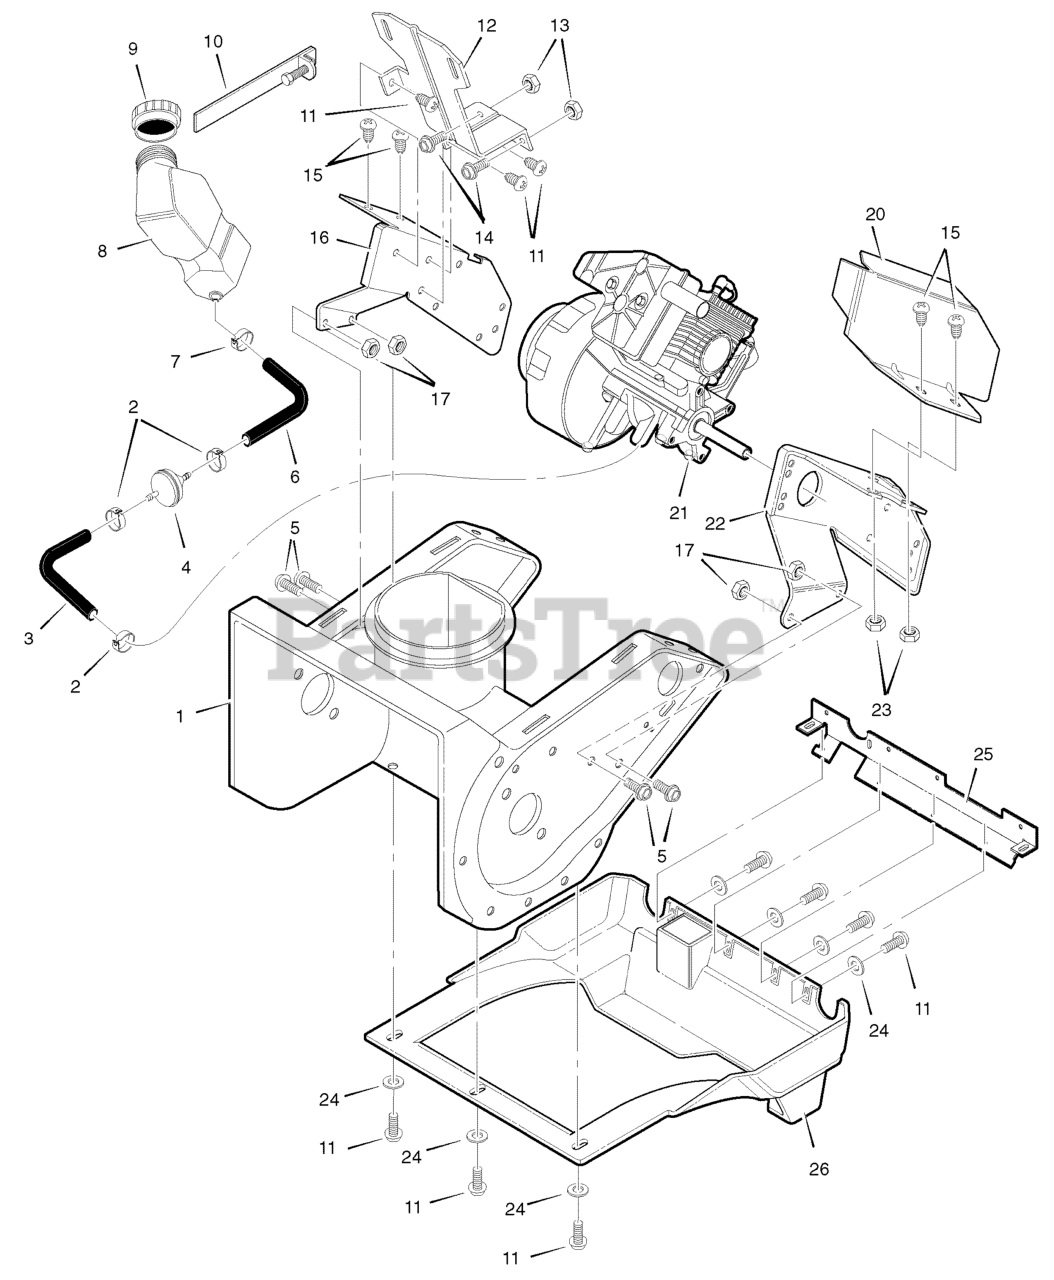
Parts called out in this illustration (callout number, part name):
1	AUGER HOUSING 21"
2	CLAMP, TUBING
3	TUBING, FUEL
4	FILTER, FUEL
5	SCREW .31-18x.50
6	TUBING, FUEL
7	CLAMP, TUBING
8	FUEL TANK
9	CAP, FUEL
10	CLAMP, WORM DR
11	SCREW 10-24x.62
12	BRACKET, FUEL TANK
13	NUT, LOCK 10-24
14	SCREW 10-24x.50
15	SCREW .25-20x.62
16	PLATE, REAR MT RH
17	NUT, LOCK .31-18
20	HEAT SHIELD
21	ENGINE
22	PLATE, REAR MT LH
23	NUT, LOCK .25-20
24	WASHER, FLAT
25	BRACKET, COVER
26	BOTTOM COVER ST0521M (621501x16NB)
